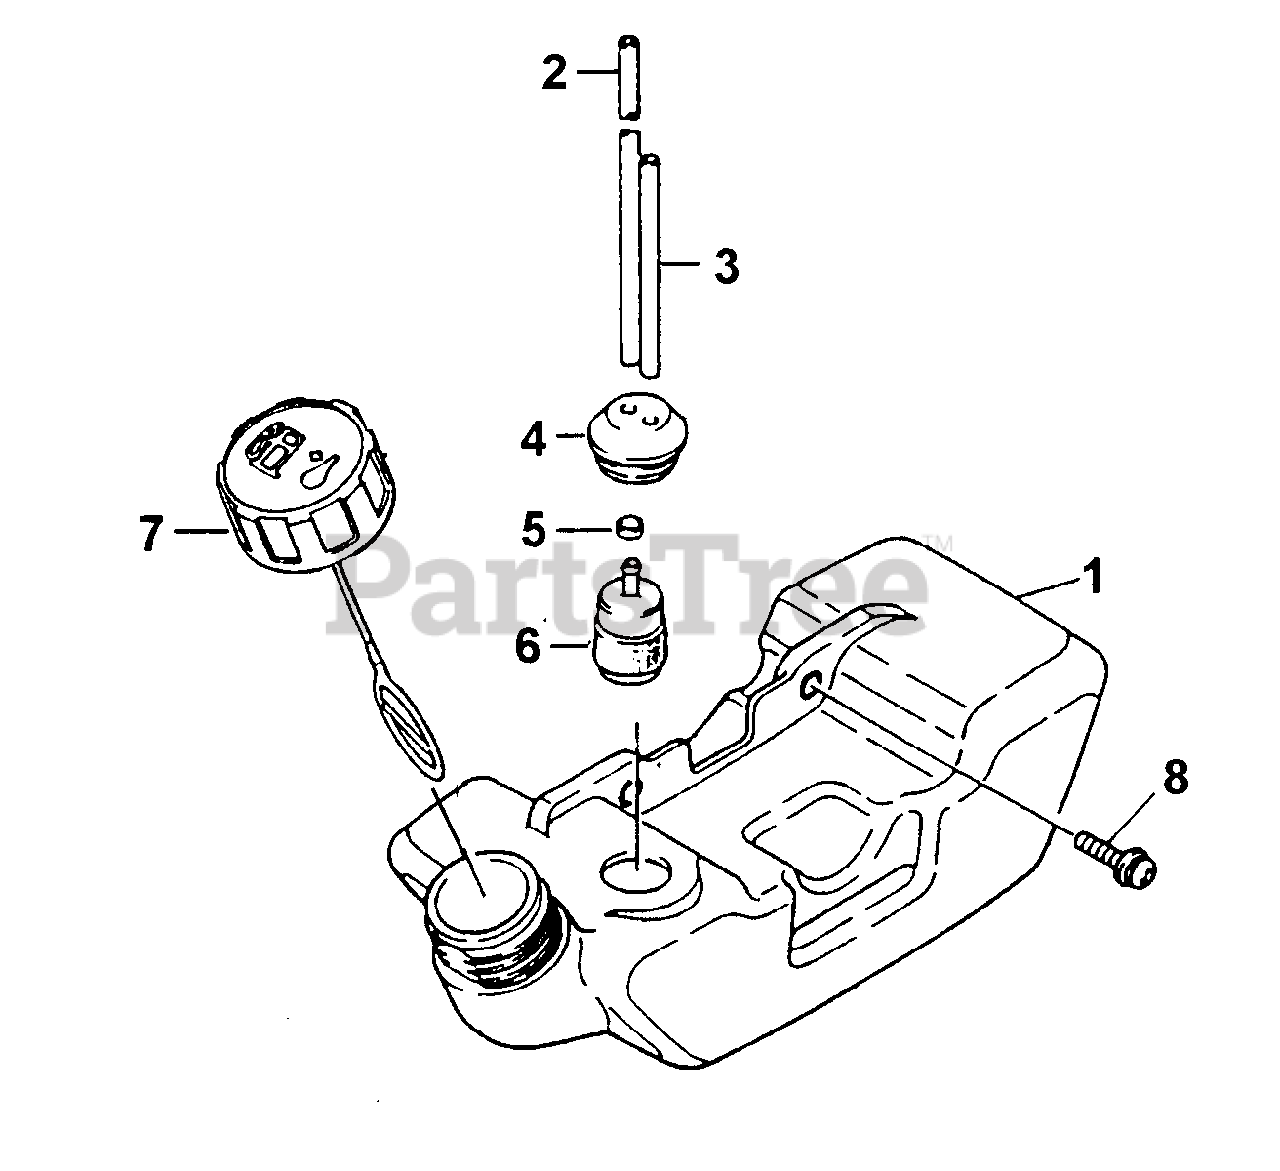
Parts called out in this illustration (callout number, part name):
1	FUEL TANK ASSY (23cc)
1	FUEL TANK ASSY (26cc)
2	TUBE, FUEL
3	TUBE, FUEL
5	BUSHING
6	FILTER, FUEL
7	TANK CAP
8	SCREW & WASHER
